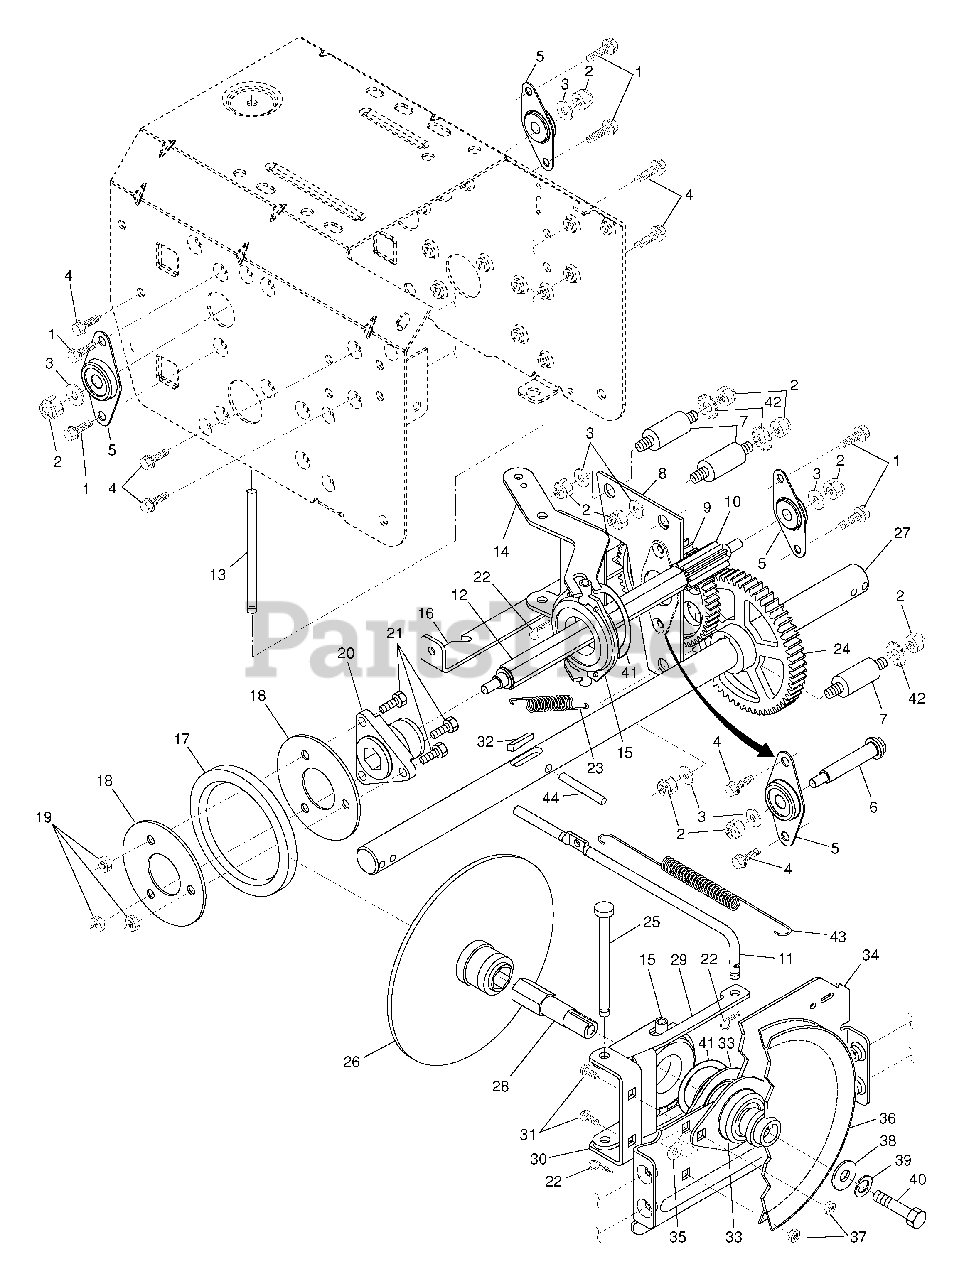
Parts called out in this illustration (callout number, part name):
1	Screw, Hex Head 5/16-18 x 5/8
2	Nut, Lock 5/16-18
3	Washer, Flat
4	Screw, Hex Head 5/16-18 x 1/2
5	Bearing, Flange
6	Shaft, Auxiliary
7	Spacer, Plate
8	Plate, Auxiliary
9	Gear, Intermediate (12/58)
10	Gear, Pinion
11	Rod, Clutch
12	Shaft, Long, Hex
13	Pin, Pivot
14	Lever, Shifter / Wheel
15	Trunnion Bearing Assembly
16	Bracket, Pivot, Shift
17	Ring, Rubber Wheel
18	Plate, Rubber Wheel
19	Nut, Lock 5/16-18
20	Hub, Rubber Wheel
21	Screw, Hex Head 5/16-18 x 7/8
22	Retainer, Hairpin
23	Spring, Bias
24	Gear, Axle (58 Teeth)
25	Pin, Pivot Lever
26	Plate Assembly, Drive
27	Shaft, Axle
28	Shaft, Short Hex
29	Lever, Shifter Plate
30	Bracket, Shifter Support
31	Bolt, Carriage 5/16-18 x 5/8
32	Key, Square
33	Bearing, Flange
34	Plate, Drive Mounting
35	Spacer, Bearing
36	Pulley, Traction Drive
37	Nut, Lock 5/16-18
38	Washer, Flat
39	Washer, Lock 5/16
40	Screw, Hex Head 5/16-18 x 3/4
41	Ring, Retaining
42	Washer, Lock, External Tooth 5/16
43	Spring, Return
